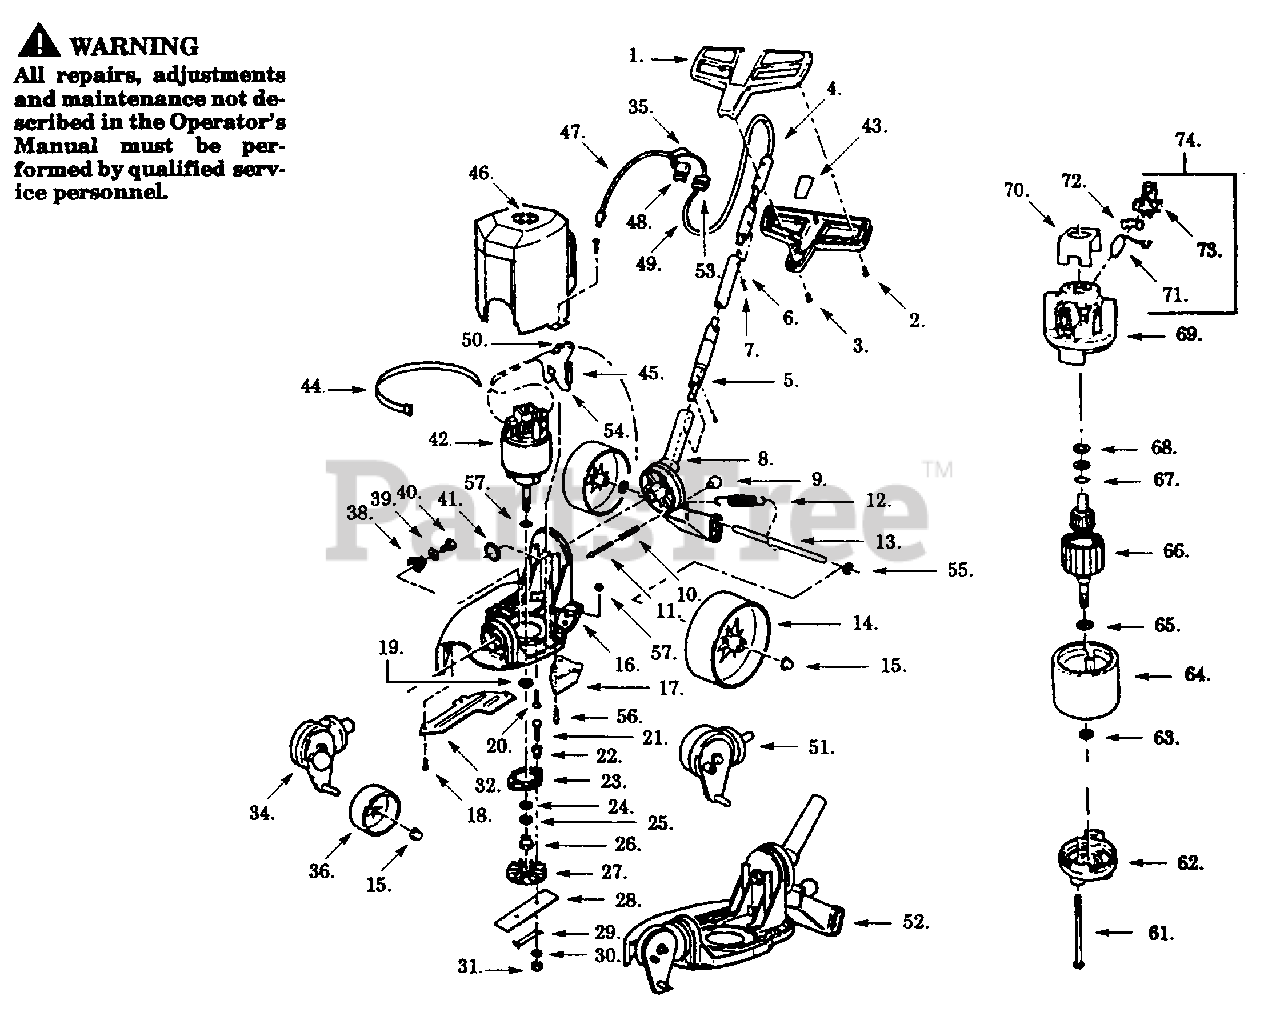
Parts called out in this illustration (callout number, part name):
1	Top & Bottom Handle
4	Upper Handle Tube
5	Lower Handle Tube
6	Lockwasher
8	Swivel Casting
12	Axle Spring
14	Rear Wheel
15	Push Nut
17	Guide Blade
22	Insulating Sleeve
23	Clutch Plate
25	Load Spring
26	Clutch Sleeve
28	Cutter Blade
29	Lock Strap
30	Lockwasher
32	Guard Plate
34	Front Swivel Ass'y.
35	Wire Nut
41	Retaining Ring
44	Tie Strap
45	Resistor
46	Motor Cover
47	Power Cord
50	Connector
51	Front Swivel Ass'y.
52	Edger Frame Ass'y.
53	P.C. Board
54	Fiberglass Sleeve
57	Lock Nut
62	Endbell (Output)
63	Field Ass'y.
64	Load Washer
65	Retaining Ring
66	Armature Ass'y.
67	Retaining Ring
69	Endbell (Brush)
70	Insulator
73	Brush Holder
74	Brush Kit (Inc.71,72,73)
